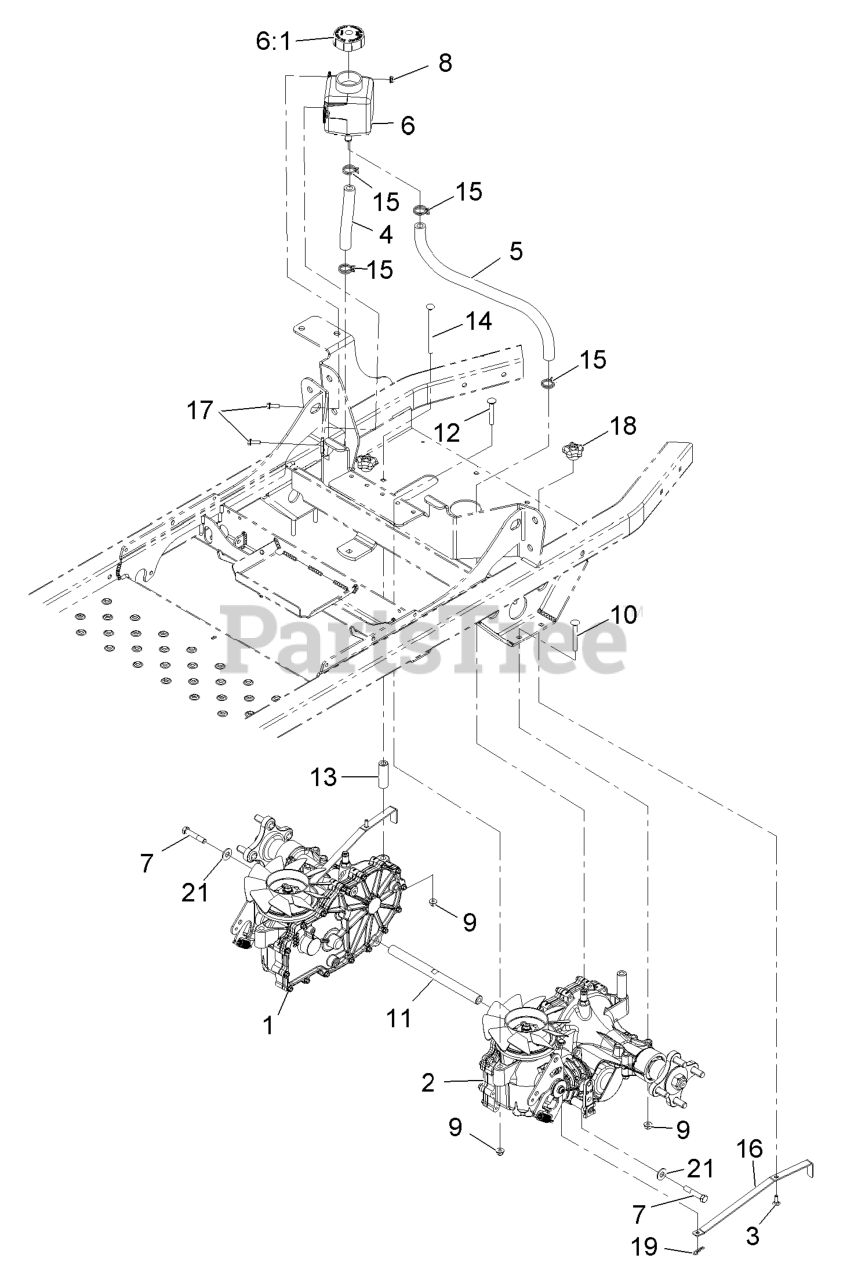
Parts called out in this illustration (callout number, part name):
1	TRANSAXLE ASM
2	TRANSAXLE ASM
3	BOLT-CARR
4	HOSE-HYDRAULIC
5	HOSE-HYDRAULIC
6	TANK-HYD
6:1	CAP-RESERVOIR, HYD
7	SCREW-HH W/LOCTITE
9	NUT-HF, NI
10	SCREW-CARR
11	SHAFT-TRANSAXLE SPACER
12	BOLT-CARR
13	SPACER-HYDRO
14	Bolt-Carriage 5/16-18 X 1 1/4
15	CLAMP-HOSE
16	ARM-BYPASS, HYDRO
17	SCREW-HWH
18	KNOB-HANDLE
19	PIN-COTTER
21	WASHER-FLAT
